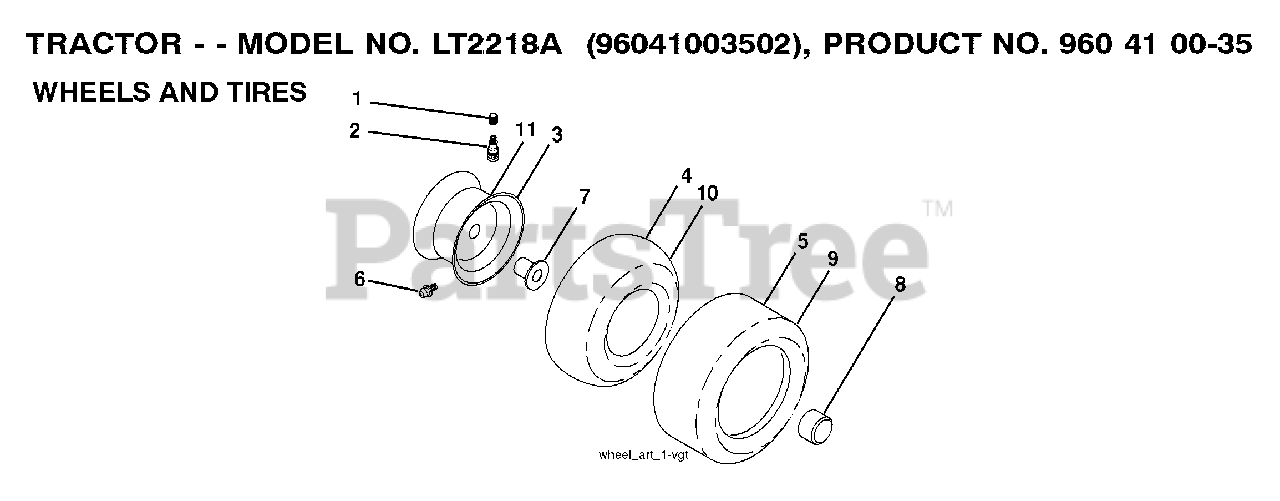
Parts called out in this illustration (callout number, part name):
1	VALVE CAP
2	VALVE STEM LT
3	RIM ASM 6" FRONT SILVER
4	TUBE.5.3/4.5/6
5	TIRE HEAVY DUTY
6	FITTING LT
7	BEARING T
8	CAP, AXLE BLK
9	TIRE.TS.20X10-8
10	TUBE
11	RIM ASM 8" REAR SILVER
